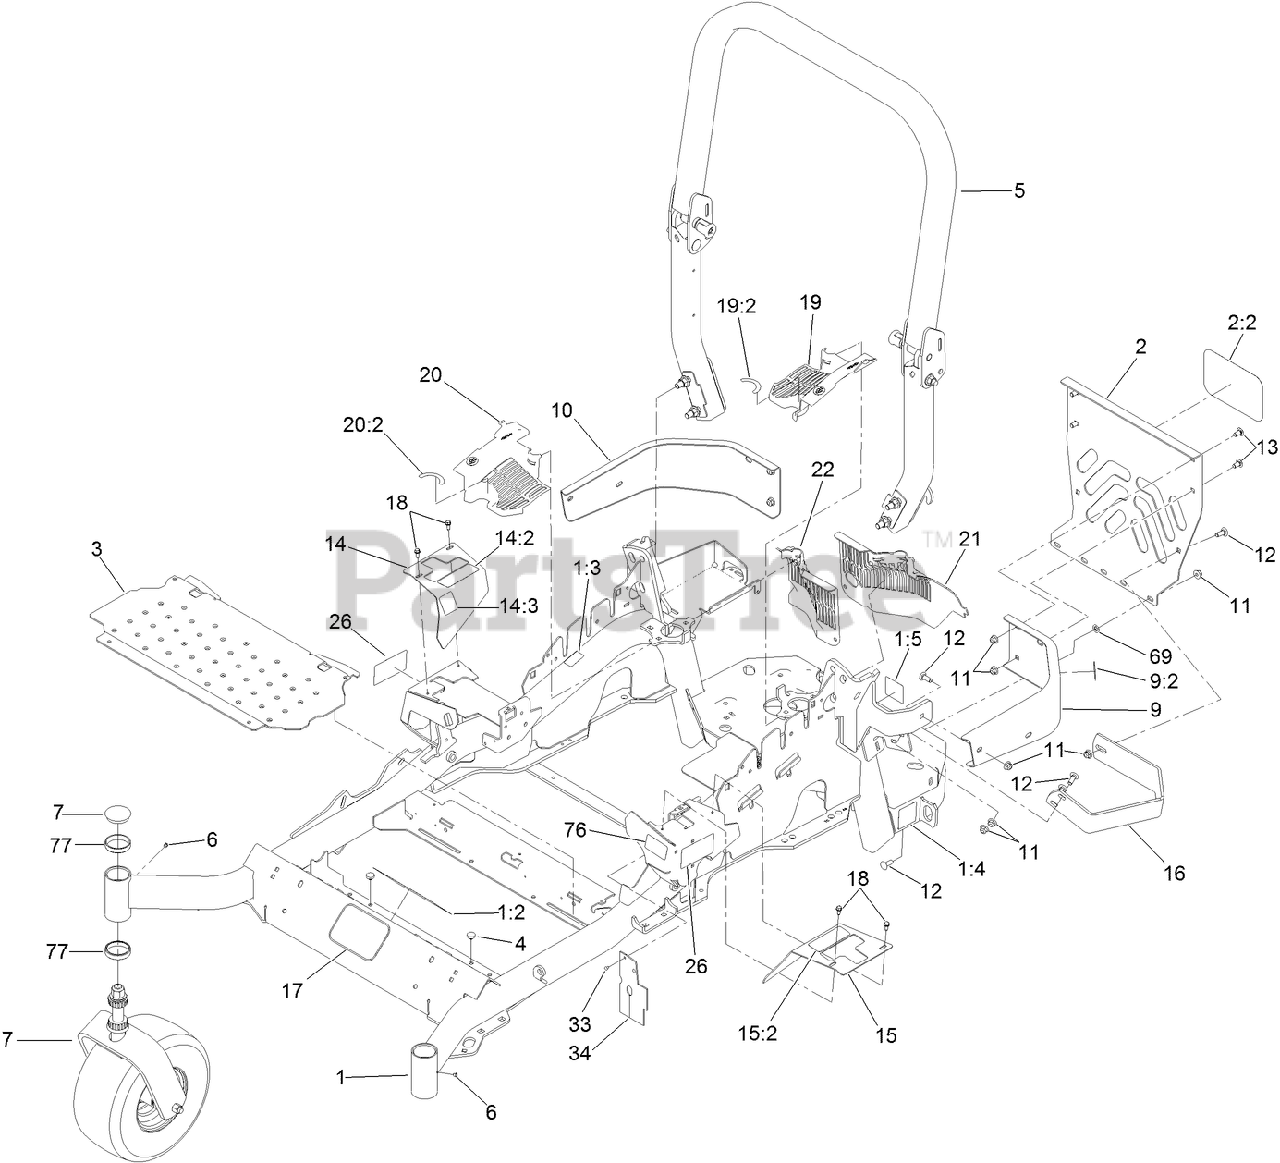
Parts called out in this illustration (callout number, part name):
1	MAINFRAME ASM
1:2	DECAL-WARNING
1:3	DECAL-WARNING, SLOPE
1:4	DECAL-HAZARD, PINCHED FINGER
1:5	DECAL-SPARK ARRESTER
2	REAR GUARD ASM
2:2	DECAL
3	FLOORPAN
4	BUMPER
5	ROPS ASM
7	Caster Wheel ASM
9	LH BUMPER ASM
9:2	DECAL-WARNING
10	BUMPER-RH
11	NUT-HF, NI
12	SCREW-CARR
13	SCREW-CARR
14	RH MOTION CONTROL COVER ASM
14:2	DECAL-CONTROL, MOTION
14:3	DECAL-PARK BRAKE, CE
15	LH MOTION CONTROL COVER ASM
15:2	DECAL-CONTROL, MOTION
16	GUARD-MUFFLER
17	DECAL
18	SCREW-HWH
19	LH HYDRO GUARD ASM
19:2	DECAL-OIL, HYDRO
20	RH HYDRO GUARD ASM
20:2	DECAL-OIL, HYDRO
21	GUARD-HYDRO, REAR (LH)
22	GUARD-HYDRO, REAR (RH)
33	RIVET-POP
34	DEFLECTOR-AIR FLOW
69	NUT-PUSH
76	DECAL-FUEL FILL, CE
77	CUP-BEARING
